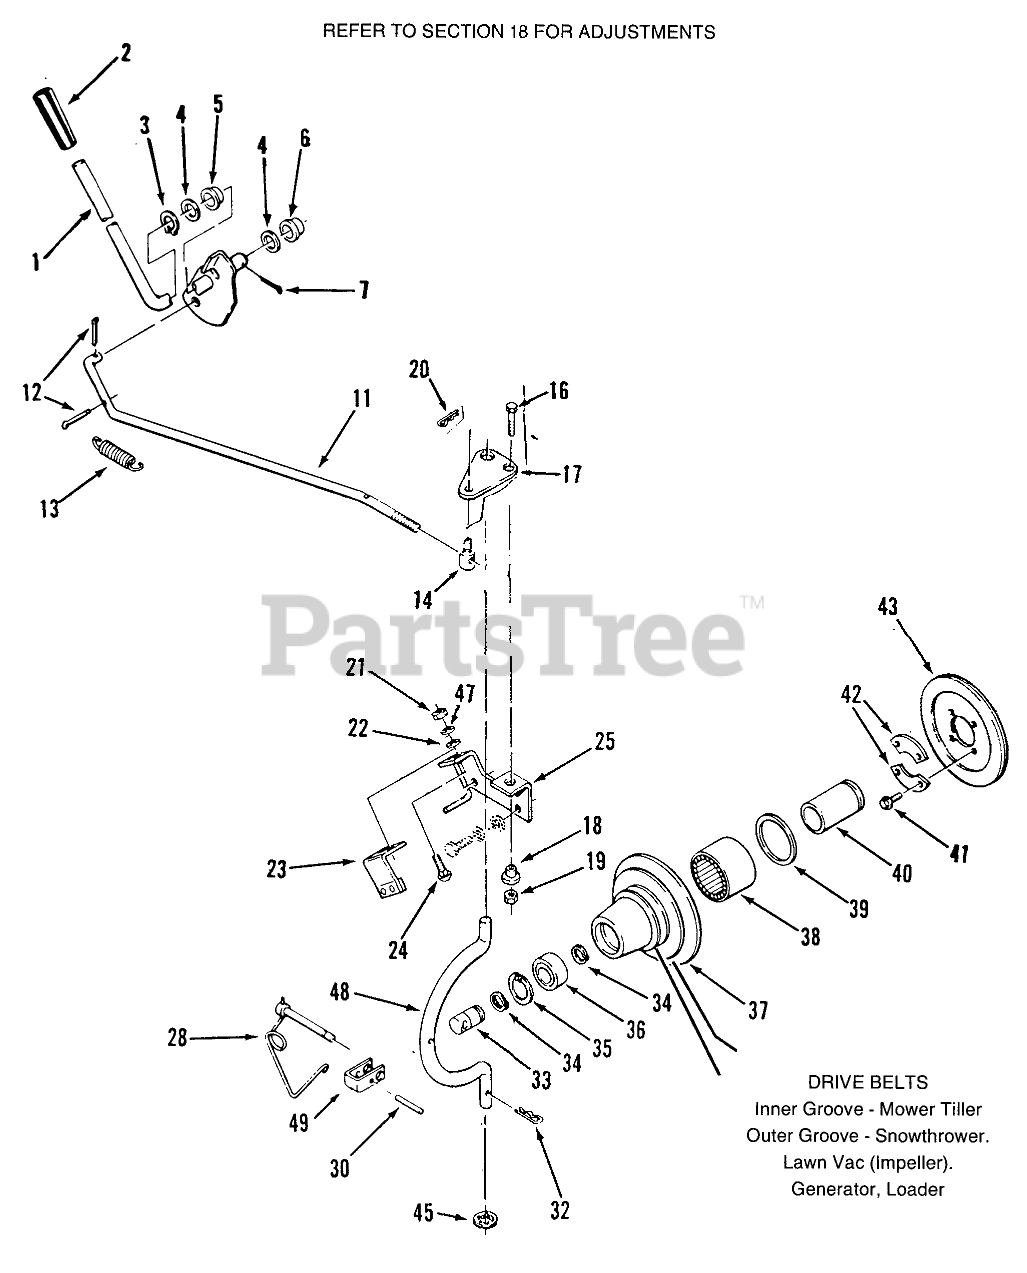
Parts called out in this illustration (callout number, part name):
1	ASSY PTO CLUTCH LEVE
2	GRIP
3	Grip Ring
4	SHIM-WASHER
5	BUSHING-NYLINER
6	NYLINER BUSHING
7	Pop Rivet
11	ROD-PTO CLUTCH
12	Pop Rivet
13	SPRING
14	TRUNNION
16	Bolt
17	PLATE
18	SPACER-LIFT LINK
19	NUT
20	Hairpin Cotter
21	Nut
23	ASM-Bracket
24	Bolt-Carriage
25	ASS'Y-ENGINE BRKT B
28	LOCKING PIN ASM
29	CLEVIS
31	ROD-HOUSING
32	Hairpin
33	SHAFT-PTO
34	RING-SNAP, EXTERNAL
35	Ring-Snap
36	BEARING-BALL
37	Housing-Clutch
38	BRG-NEEDLE OPEN END
39	SEAL-OIL
40	RACE-BEARING
41	H H C S
42	RETAINER
43	Facing-Clutch
45	RING-REINFORCED CIRC
47	Washer
